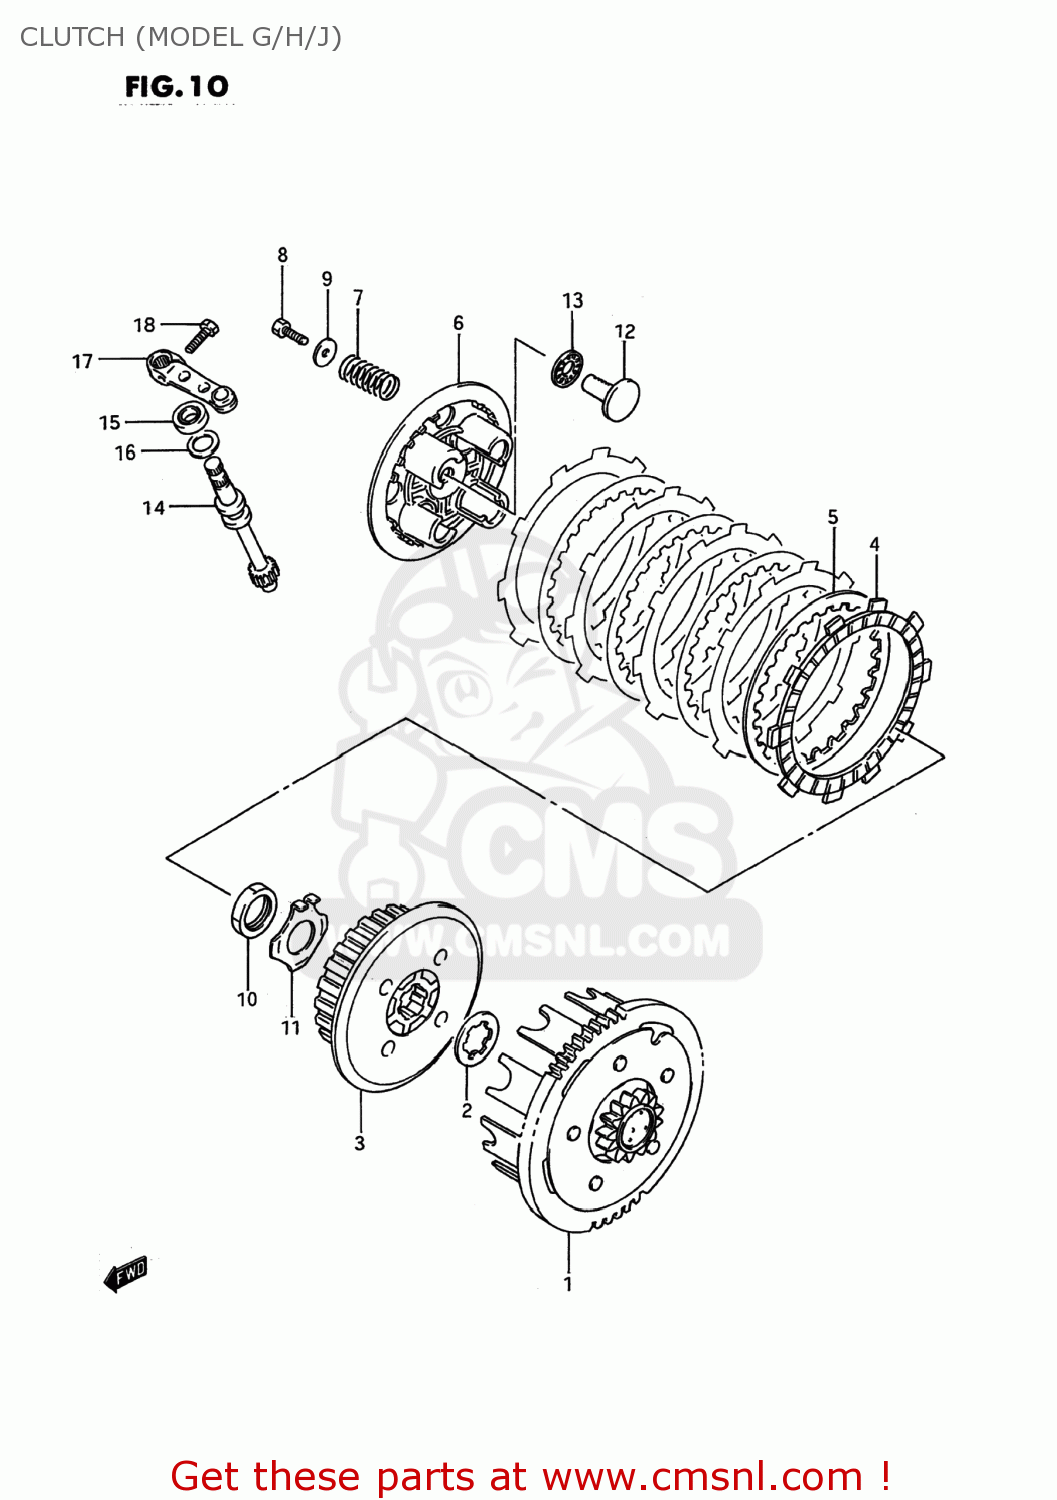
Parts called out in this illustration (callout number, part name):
1	GEAR ASSY,PRI DRIVEN
2	WASHER,LOCK
3	HUB,CLUTCH SLEEVE
4	PLATE,CLUTCH DRIVE (NAS)
5	PLATE,CLUTCH DRIVEN (NAS)
6	DISC,CLUTCH PRESSURE
7	SPRING
8	BOLT(5X16)
9	WASHER (5.5X16X1.2)
10	NUT
11	WASHER
12	RACK,CLUTCH RELEASE
13	BEARING(10X22X2.8)
14	PINION,CLUTCH RELEASE
15	SEAL,OIL(10X17X5)
16	WASHER (12X17X1)
17	ARM,CLUTCH RELEASE
18	BOLT
